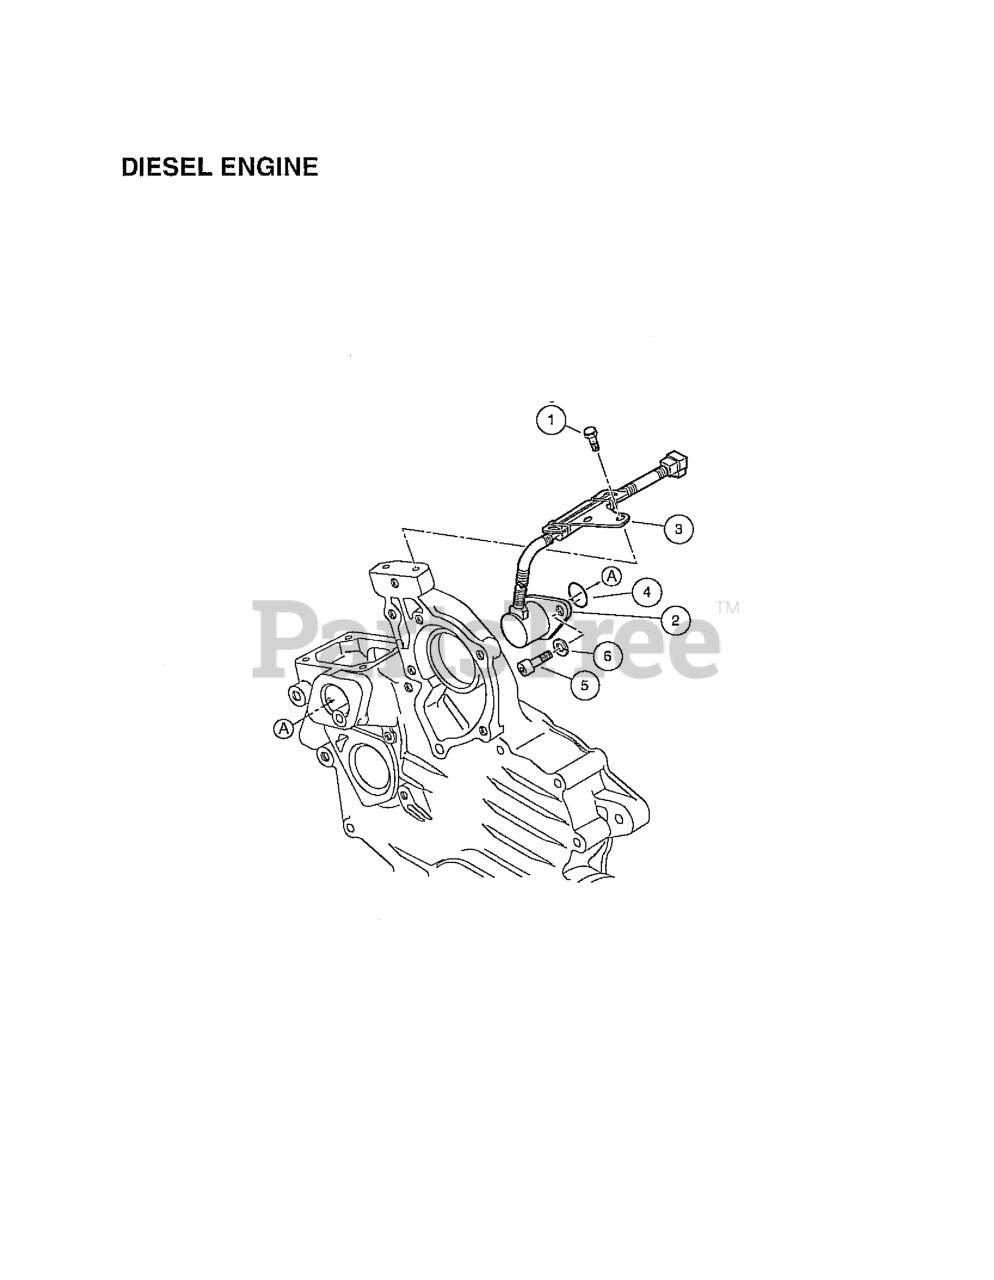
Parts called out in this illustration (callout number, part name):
1	BOLT, SOLENOID, STOP, D722
2	SOLENOID-STOP
3	STAY-SOLENOID
4	BALL-CHECK-D722CB
5	BOLT-SOLENOID-STOP
